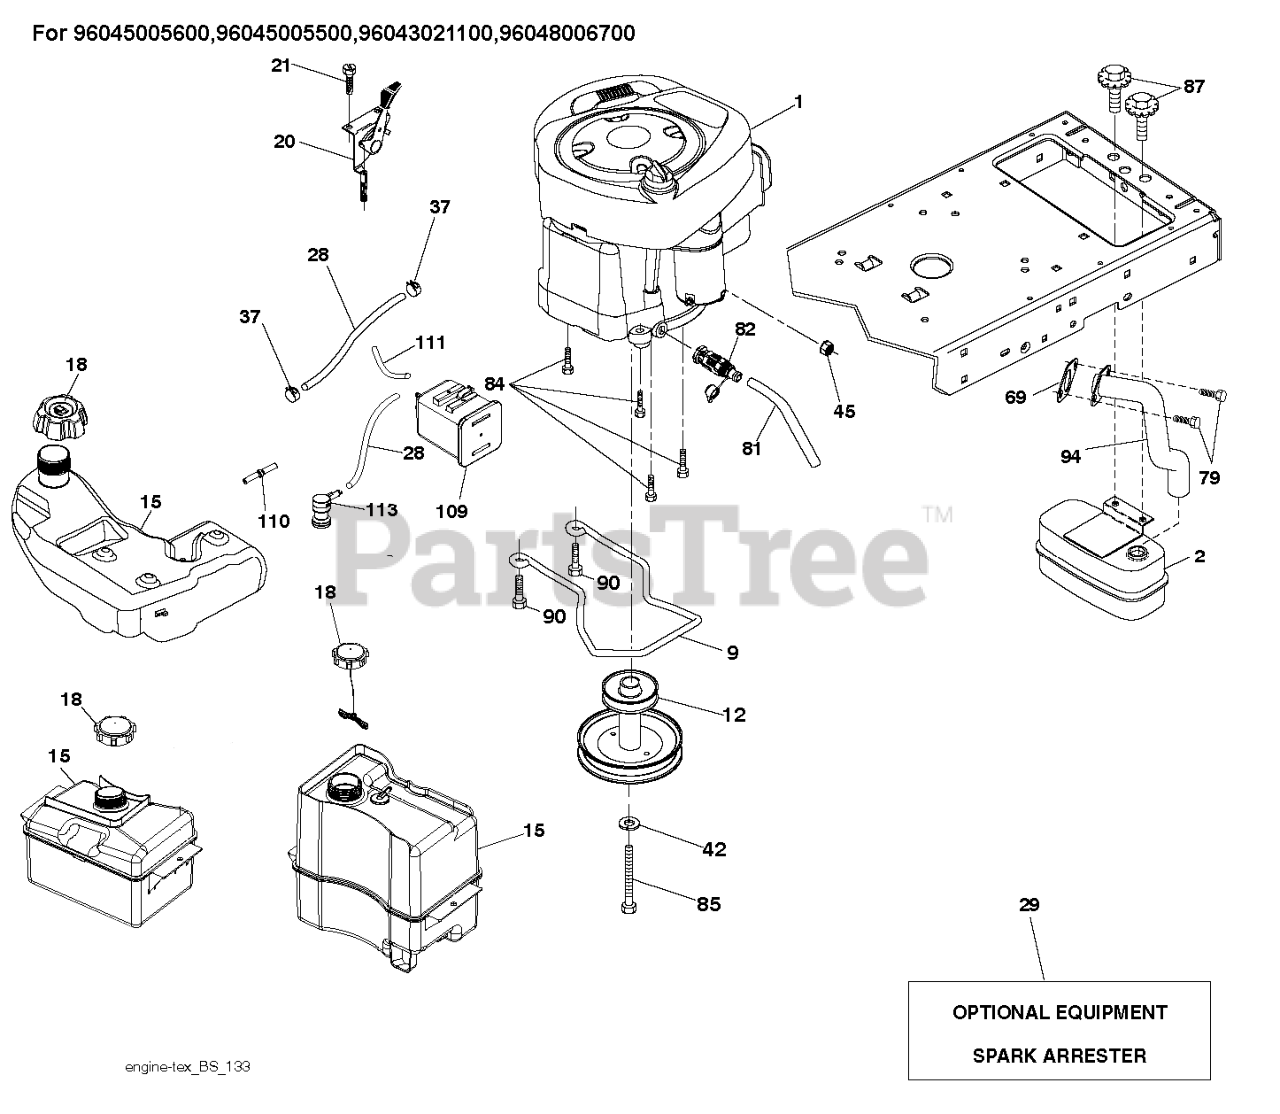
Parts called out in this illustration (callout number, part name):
2	MUFFLER.ASM.SINGLE
9	KEEPER.BELT.ENG.3.25"2BOLT.PNT
12	PULLEY.ENGINE
15	TANK.ASM.FT.2.5GAL.W/CAP.EPA17
15	TANK.ASSEMBL.2.5GAL.NON-EPA
15	TANK.ASM.FUEL.3GA.CARB.17
18	CAP ASM.FUEL.2.25"FR.
18	CAP.FUEL.2 WAY VENT
18	FUEL CAP
18	CAP ASSY FUEL 3" GRAY
20	HANDLE.PARKING.BRAKE.H (BLK)
20	CONTROL.TH/CK.C.
21	SCREW.#10 X 0.750.BOS
28	LINE.FUEL.64"REAR.EMIS
28	LINE.FUEL.20"FRONT.EMI
29	KIT.SPARK ARRESTOR 794945 B&S
37	HOSE CLAMP
42	WASHER 7/16 LOCK
42	LOCKWASHER
45	NUT
69	REPL BY 532 27 22-93
79	SCREW.SOCKET HD.5/16-1
81	TUBE, DRAIN OIL ASM.
82	VALUE.OIL.DRAIN
84	SCREW.3/8-16
85	BOLT HEX 7/16-20X4-1/4"
87	BOLT.5/16-18UNCX3/4 W/SEMS.BLK
90	SCREW 3/8-16X1
94	EXHAUST.TUBE.B&S.28/31
109	CANNISTER, CARBON
110	VALVE.ASM.ANTI-SLOSH
111	RP PURGE LINE
113	VALVE.SLANT.CARTRDG.90 DEG.TEX
